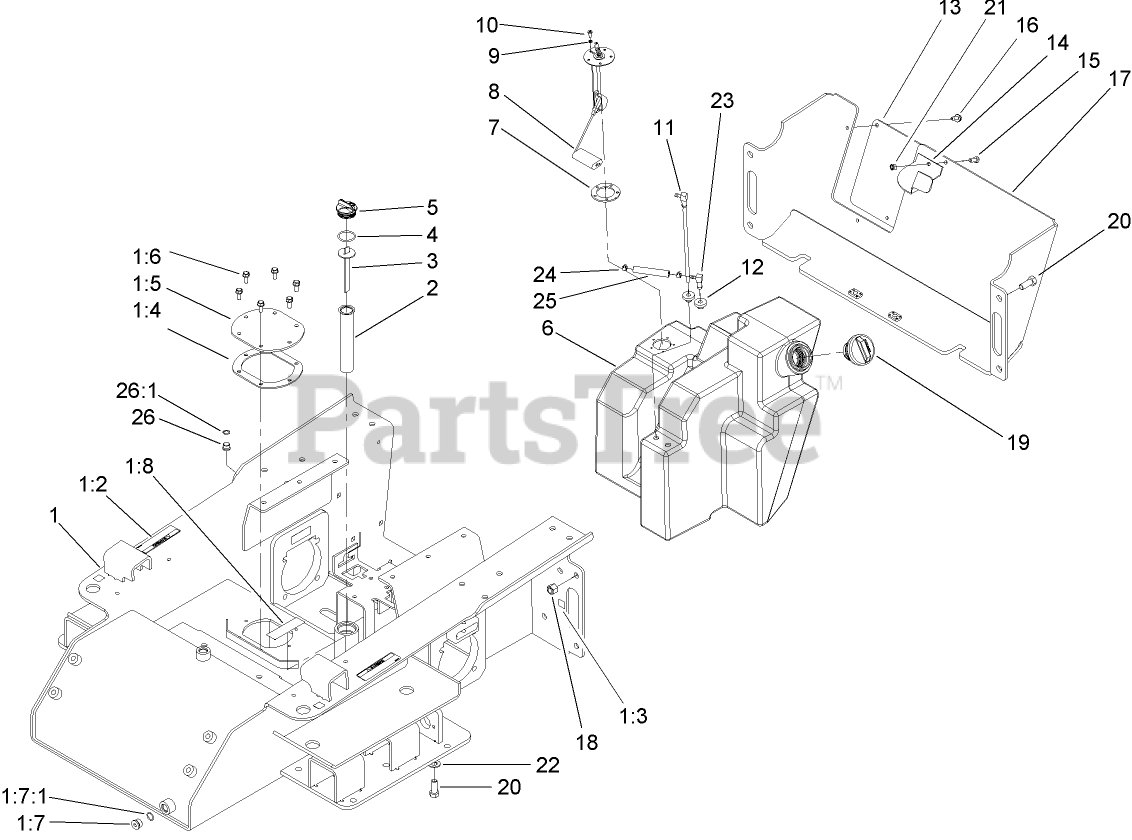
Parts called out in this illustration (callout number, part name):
1	CHASSIS ASM
1:2	DECAL-WARNING, PINCH
1:3	DECAL-POINT, LIFT
1:4	GASKET-COVER, ACCESS
1:5	COVER-TANK
1:6	SCREW
1:7	PLUG-HEX
1:7:1	O-RING
1:8	DECAL-OIL, HYD
2	FILTER-SCREEN
3	DIPSTICK-OIL
4	O-RING
5	PLUG-PLASTIC
6	TANK-FUEL, DIESEL
7	GASKET-SENDER, FUEL
8	SENDER-FUEL
9	WASHER-LOCK
10	SCREW-PPH
11	PIPE-STAND
12	BUSHING
13	PANEL-REAR
14	CLAMP-TANK, FUEL
15	SCREW-HH
16	SCREW-HWHTF
17	REAR CHASSIS ASM
18	NUT-LOCK, NI
19	CAP-FUEL
20	SCREW-HH
21	NUT-LOCK, NI
22	WASHER-FLAT
23	FITTING-ELBOW, 90 DEG
24	CLAMP-HOSE
25	HOSE-LP
26	PLUG-HEX, HOLLOW
26:1	O-RING
